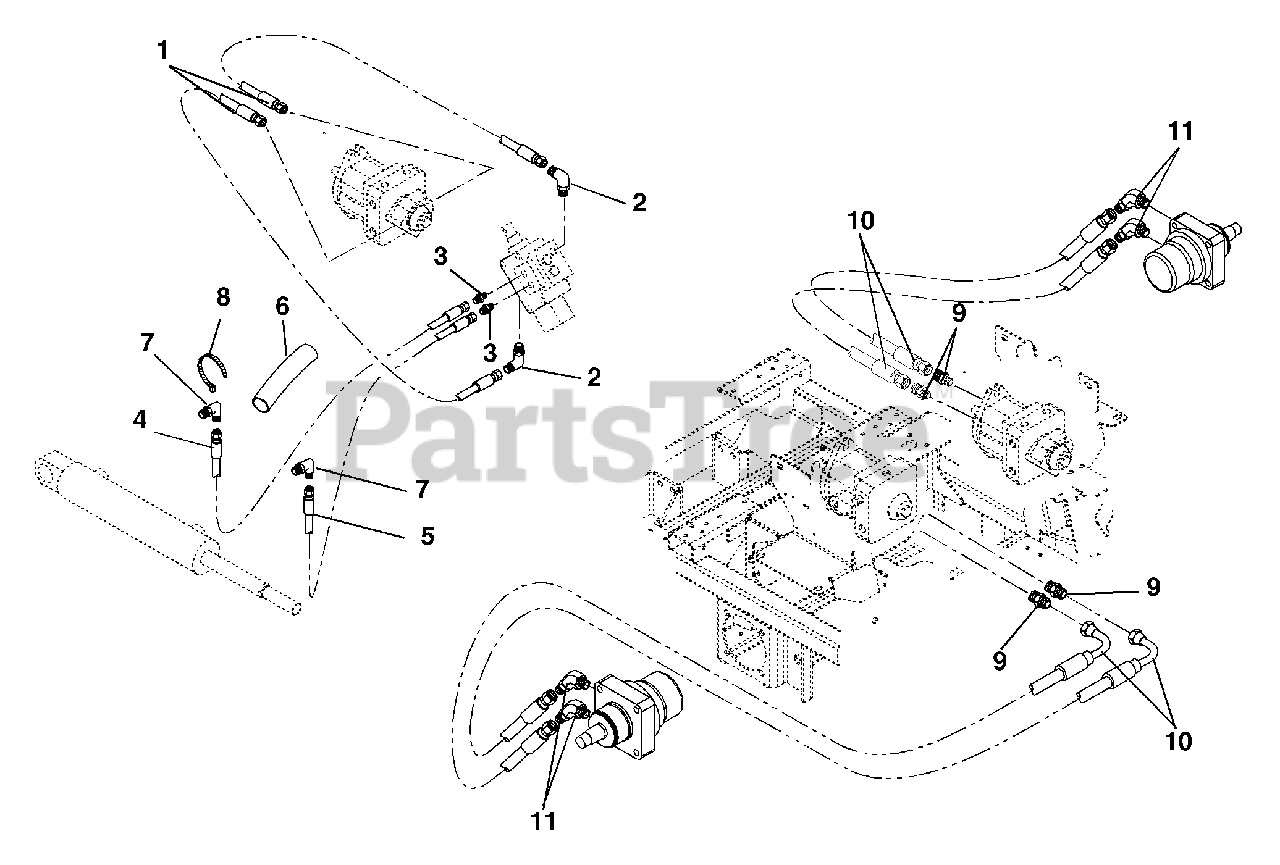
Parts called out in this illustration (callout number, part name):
1	HOSE,HYD.25-22-2K F04F9-F06FO
2	FTG, HYD ELBOW M6F-M8O
3	FITTING, HYD (4-6 F5OLO)
4	HOSE,HYD.25-42-2K F04F0-F04F4
5	HOSE,HYD .25-47-2K F04F0-F04F4
6	SLEEVE, PROTECTIVE
7	FITTING, HYD (4 C5OLO)
8	CABLE TIE LG 5-1/2
9	ADPTR,FACE SEAL 8X8 1/2 O-RING
10	HOSE,HYD .50-17-2K F08F0-F08F9
11	FITTING, HYD (8-10 V5OLO)
